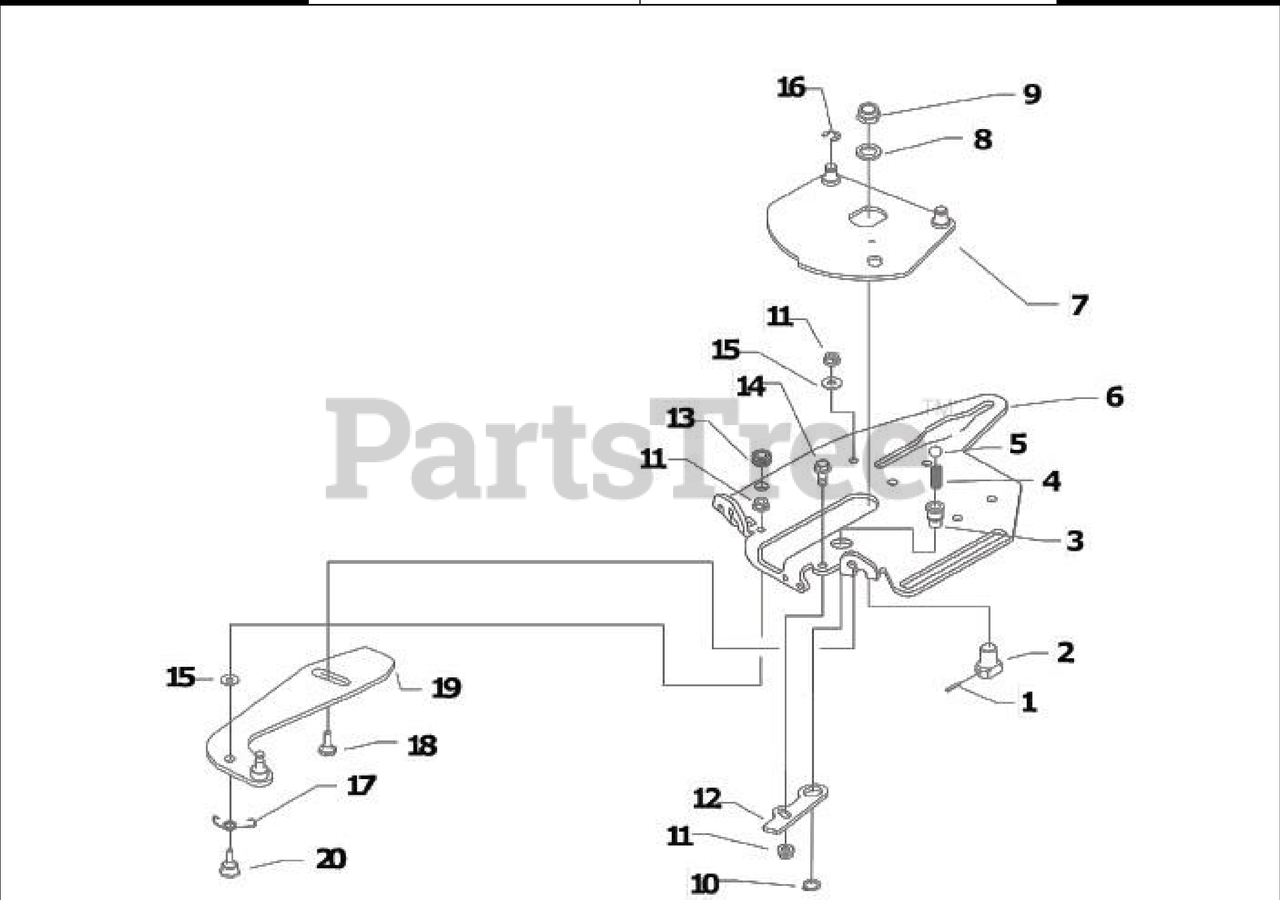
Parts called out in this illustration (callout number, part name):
1	ROLL PIN
2	SLEEVE
3	SLEEVE
4	SPRING
6	DRIVE PLATE
7	BUTTERFLY PLATE
8	WASHER 19
9	SELFLOCK NUT M18X1.5
10	SNAP RING E 18 DIN 471
11	SELFLOCK NUT M8 6S
12	LEVER
13	CABLE CLAMP 11-55-21-5
14	SCREW TE C/F M8X20 DIN 6921
15	WASHER 8.4
16	SNAP RING E 5 UNI 7434
17	SPRING
18	LOCKING BOLT
19	PTO PLATE
20	LOCKING BOLT
